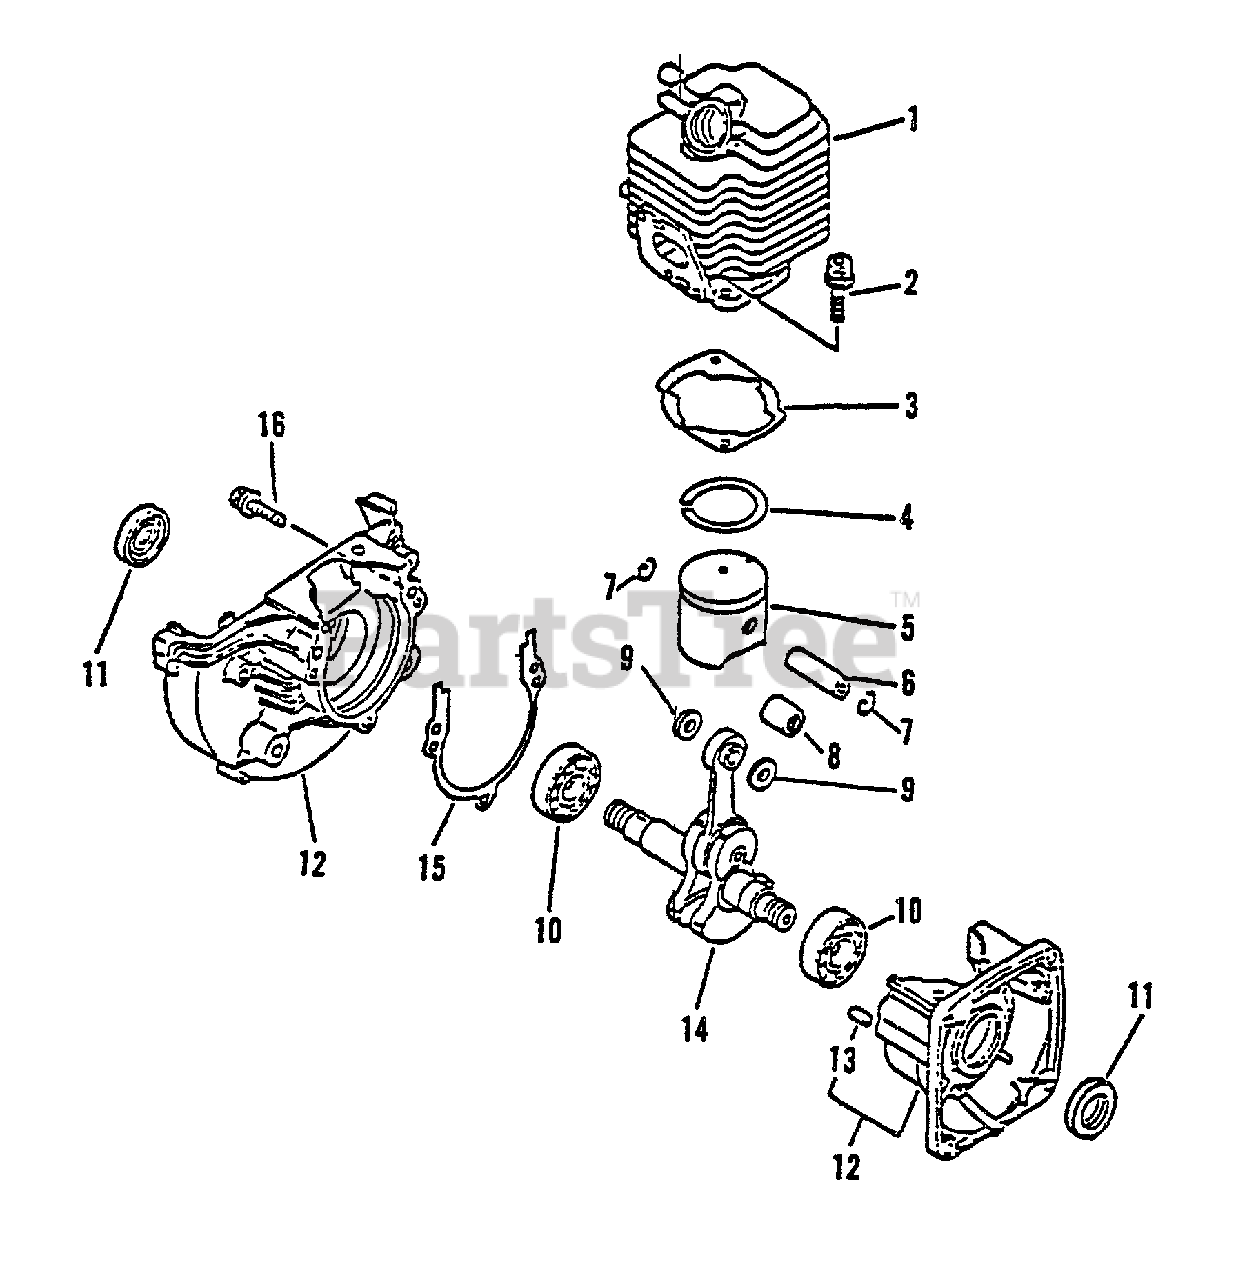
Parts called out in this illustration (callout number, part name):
1	CYLINDER
2	BOLT 5×22
3	GASKET, CYLINDER
4	RING, PISTON
5	PISTON KIT
6	PIN, PISTON 8
7	RING, SNAP
8	BEARING, NEEDLE
9	WASHER, THRUST
10	BEARING, BALL - 6201 C3
11	SEAL, OIL 12
12	CRANKCASE KIT
13	PIN, LOCATING 4
14	CRANKSHAFT ASSY
15	GASKET, CRANKCASE
16	BOLT 5×28
